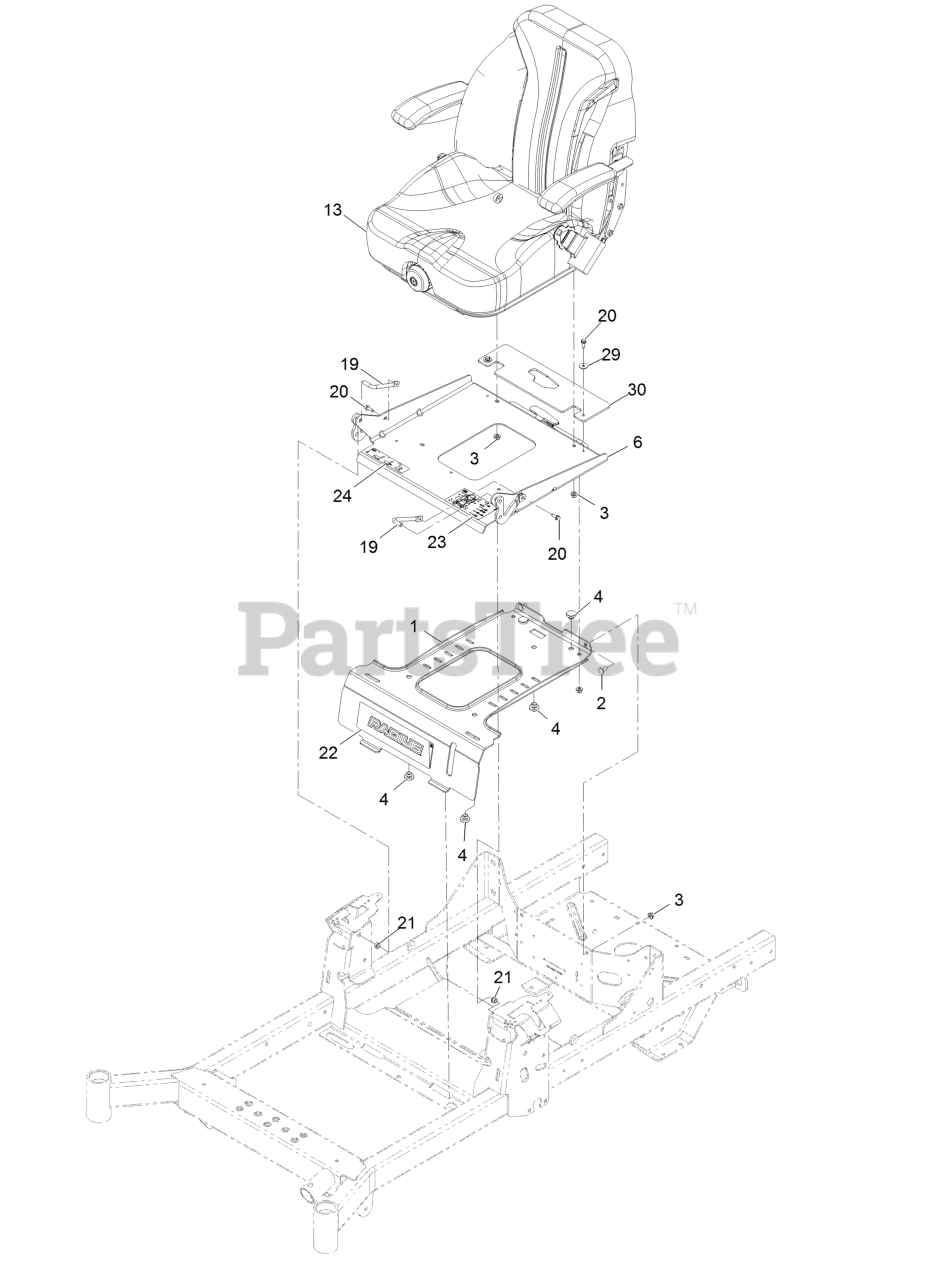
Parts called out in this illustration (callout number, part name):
1	Plate-Retainer, Tank
2	Bolt-Carriage 5/16-18 X 3/4 Short Neck
3	Nut-Nyloc 5/16-18 Flg
4	Bumper-Seat
6	Seat Pan And Latch ASM
13	ASM-Susp Seat
19	Pin-Pivot, Seat
20	Screw-HWH 1/4-20 X 3/4
21	Bushing-Flanged
22	Decal-Radius Logo
23	Decal-Aid, Service
24	Decal-Latch, Seat
30	Guard-Seat, Rubber
